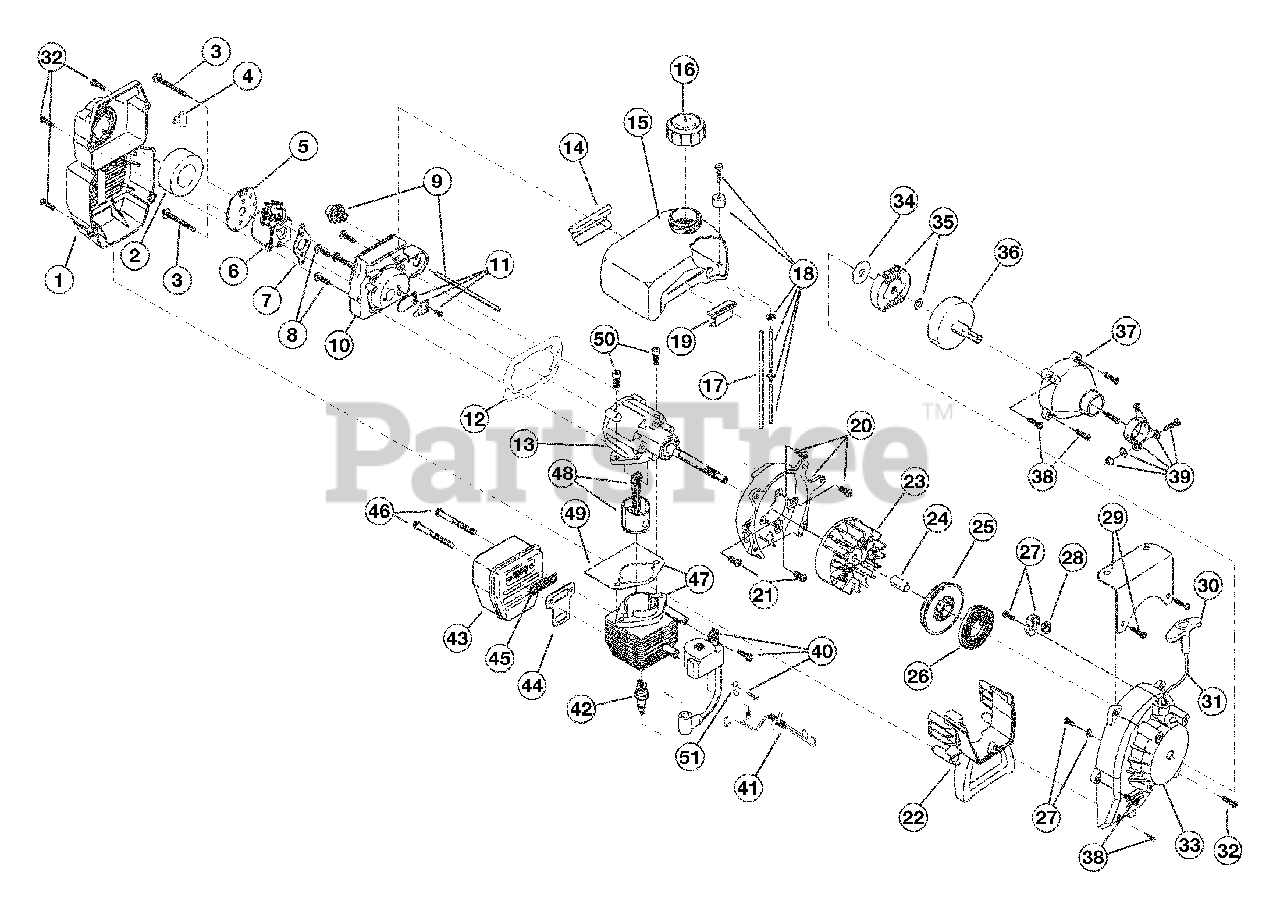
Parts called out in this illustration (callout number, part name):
1	Air Cleaner/Muffler Cover Assembly
2	Air Cleaner Filter
3	Carburetor Mounting Screw Assembly
4	Choke Lever
5	Choke Plate
6	Carburetor Assembly
7	Carburetor Gasket
8	Carb Mount Screw
9	Primer and Hose Assembly
10	Carb Mount Assembly
11	Reed Assembly
12	Carburetor Mount Gasket
13	Crank Case Service Assembly
14	Rear Mounting Pad
15	Fuel Tank Assembly
16	Fuel Cap Assembly
17	Fuel Return Line
18	Fuel Line Assembly
19	Front Mounting Pad
20	Shroud Assembly
21	Shroud Screw
22	Shroud Extension & Stand
23	Flywheel Assembly
25	Recoil Pulley Assembly
26	Recoil Spring
27	Pulley Retainer Assembly
28	Rope Guide
29	Fuel Tank Guard Assembly
30	Pull Handle
32	Housing Screw
33	Starter Housing Assembly
34	Clutch Washer
35	Clutch Rotor Assembly
36	Clutch Drum Assembly
37	Clutch Cover Assembly
38	Cover Screw
39	Upper Clamp Assembly
40	Module Assembly
41	Wire Lead
42	Spark Plug
43	Muffler Assembly
44	Exhaust Gasket
45	Spark Arrestor
46	Muffler Mounting Bolt Assembly
47	Cylinder Assembly
48	Piston and Rod Assembly
49	Cylinder Gasket
50	Cylinder Bolt
51	Ground Tab
